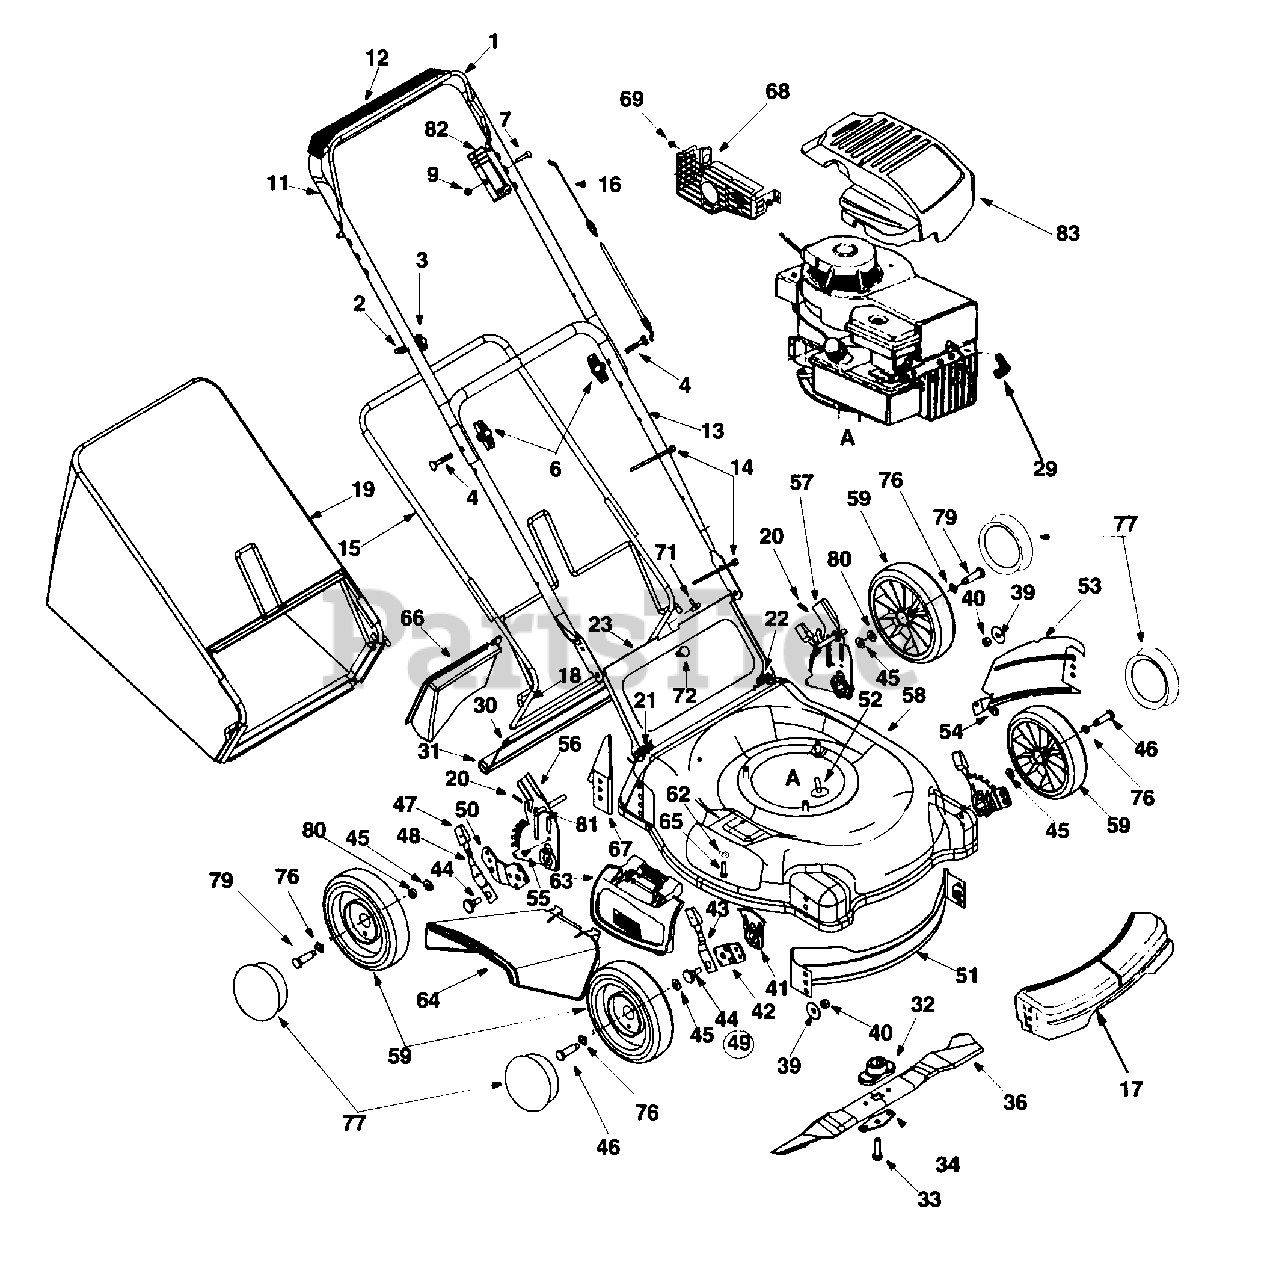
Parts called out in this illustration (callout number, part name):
1	Control Handle Assembly
2	Rope Guide
3	Handle Knob 1/4-20 Thd.
4	Curved Hd. Bolt 5/16-18 x 2" Lg.
6	Hand Knob
7	Oval C-Sunk Mach. Scr.
9	Hex L-Nut 1/4-20 Thd.
14	Cable Tie
16	Control Cable - 39"
17	Front Cover: Black
20	Int. Cotter Pin 5/16" Dia.
21	Door Spring - R.H.
22	Door Spring - L.H.
30	Wire Rod
31	Rear Flap
32	Blade Adapter
33	Hex Bolt 3/8-24 x 1.5" Lg.
34	Blade Bell Support
36	21" Mulching Blade
39	Bell-Wash..39" I.D. x 1.38"
40	Hex Nut 3/8-16 Thd.
41	Height Adj. Plate
43	Front Spring Lever Ass'y. w/Knob
44	Shld. Bolt.5" Dia. x .357"
45	Bell-Wash..38" I.D. x .88" O.D.
46	Front Axle Bolt
47	Spring Lever Knob
48	Rear Spring Lever
49	Height Adj. Assy. Comp. - RH
50	Pivot Bar R.H.
54	Torx Mach AB-Tap Scr. 1/4 x.62"
55	HexInd Wash. Scr. 1/4-14:.625
56	Handle Brkt. Ass'y.-- RH
57	Handle Brkt. Ass'y.-- LH
62	Bell-Washer 1/4" I.D.
63	Hinged Mulching Plug
64	Chute Deflector: Side Discharge
65	Hex Hd Self-Tp Scr. 1/4-20 x .5' L.
66	Mulching Baffle Plug
68	Muffler Guard
69	Hex Washer Head Screw
71	Truss Scr. #10-24 x .38" Lg.
76	Wave Washer
77	Hub Cap - Rad. Spoke - Beige
79	Rear Axle Bolt
80	Spacer
82	Control Housing w/o Lever
83	Engine Shroud
